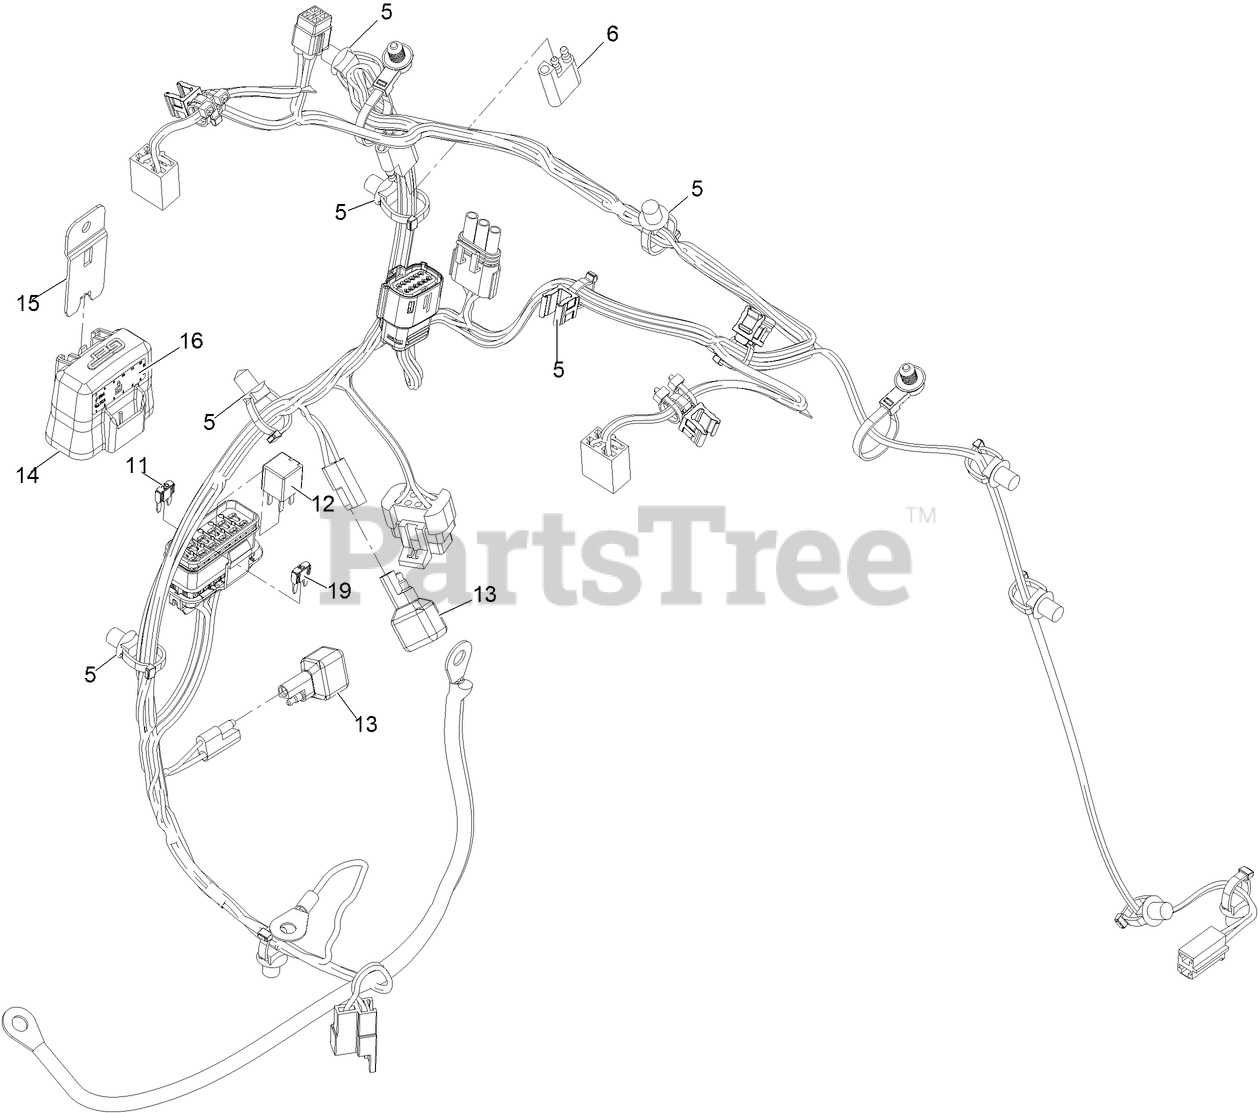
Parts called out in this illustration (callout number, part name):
5	CLIP-TIE
6	Cap-Plug
11	FUSE-MINI BLADE, 20 AMP
12	RELAY-MICRO
14	COVER-BLOCK, FUSE
15	CLIP-MOUNTING
16	DECAL-FUSE
19	FUSE-MINI BLADE, 15 AMP
